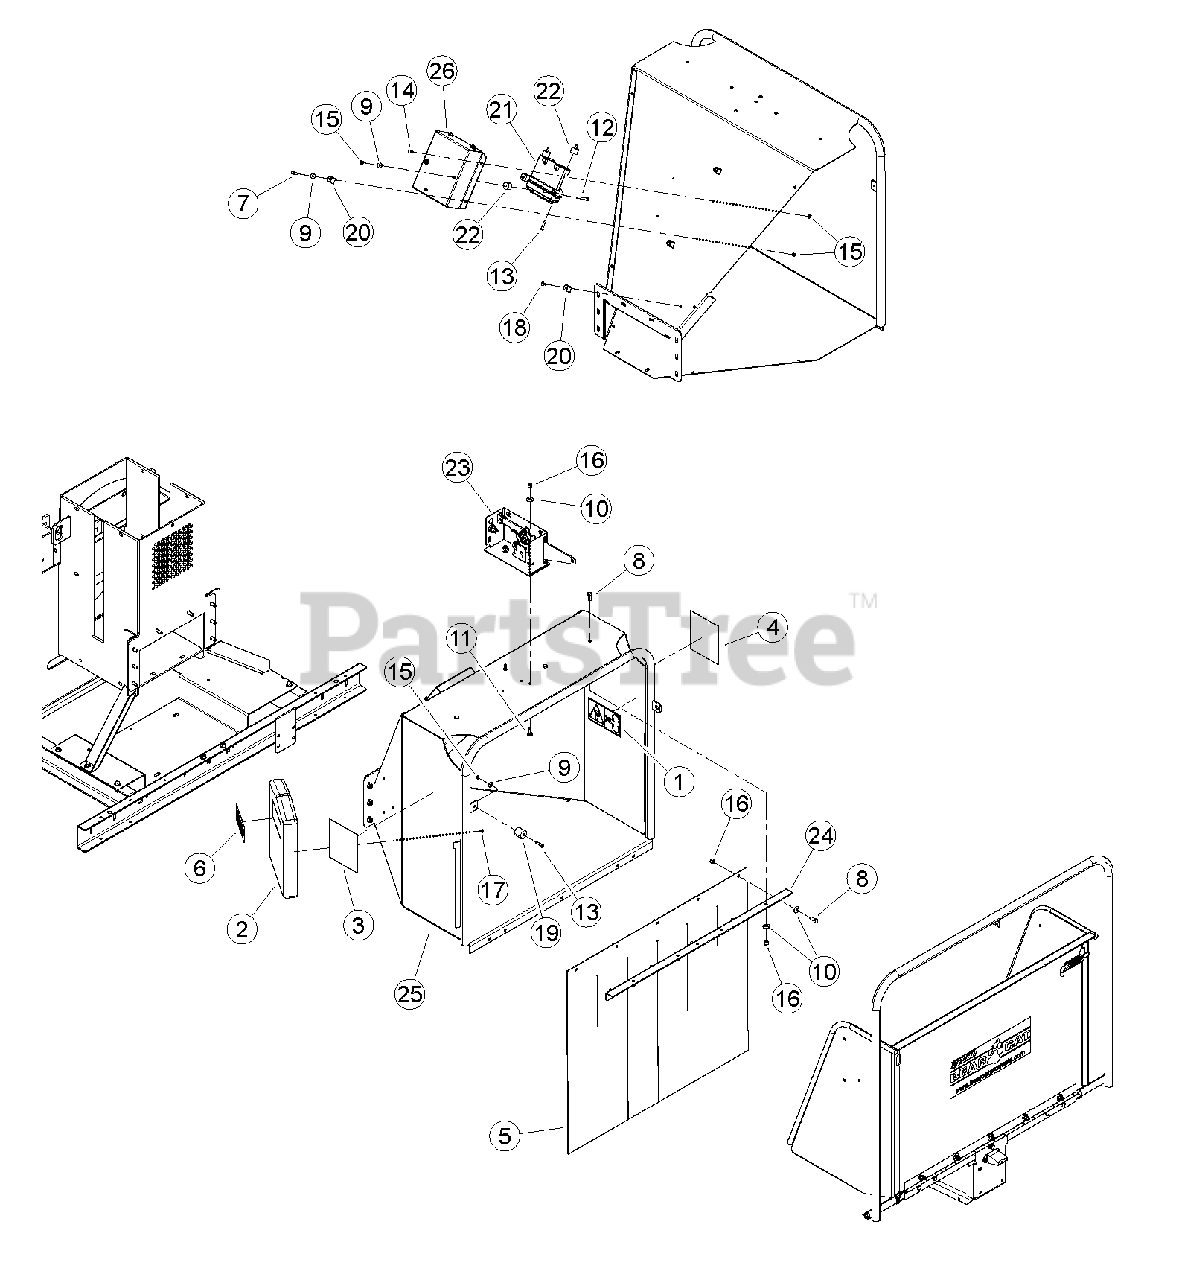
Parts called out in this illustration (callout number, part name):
1	DECAL, BLADE DANGER ISO
2	CONTAINER, INSTR. MANUAL
3	DECAL, FEED POSITION
4	DECAL, FEED POSITION
5	FLAP, CHUTE
6	DECAL, MUTILINGUAL MANUAL
7	BOLT, 1/4 X 1 GR5 HEX HD ZP
8	BOLT, 3/8 X 1 HEX HD GR5 ZP
9	WASHER, 1/4" FLAT ZP
10	WASHER, 3/8" FLAT ZP
11	BOLT, 3/8 X 1" GR5 CRG NC ZP
12	BOLT, 1/4 X 2-1/4 G5 HCS ZP
13	BOLT, 1/4-20 X 1-1/4 GR5 HHCS MAGNI 565 SILVER
14	BOLT, 1/4 X 5/8" HHCS GR5 ZP
15	NUT, 1/4" NE NYLOCK ZP
16	NUT, 3/8" NE NYLOCK ZP
17	RIVET, AL BLIND 1/4 X 1/2 DOME HEAD
18	RIVET, AL BLIND 1/4 X 3/4 DOME HEAD
19	BUMPER, RECESSED RUBBER
20	CLAMP, CABLE MOUNT
21	CONTROLLER, PLUS 1 CHIPPER
22	BUMPER, 1" OD W/ 1/4" STUD
23	ASSEMBLY, SWITCH BOX
24	SUPPORT, CHIPPER FLAP
25	WELDMENT, CHIPPER CHUTE
26	ENCLOSURE, PLUS 1 MOUNT
